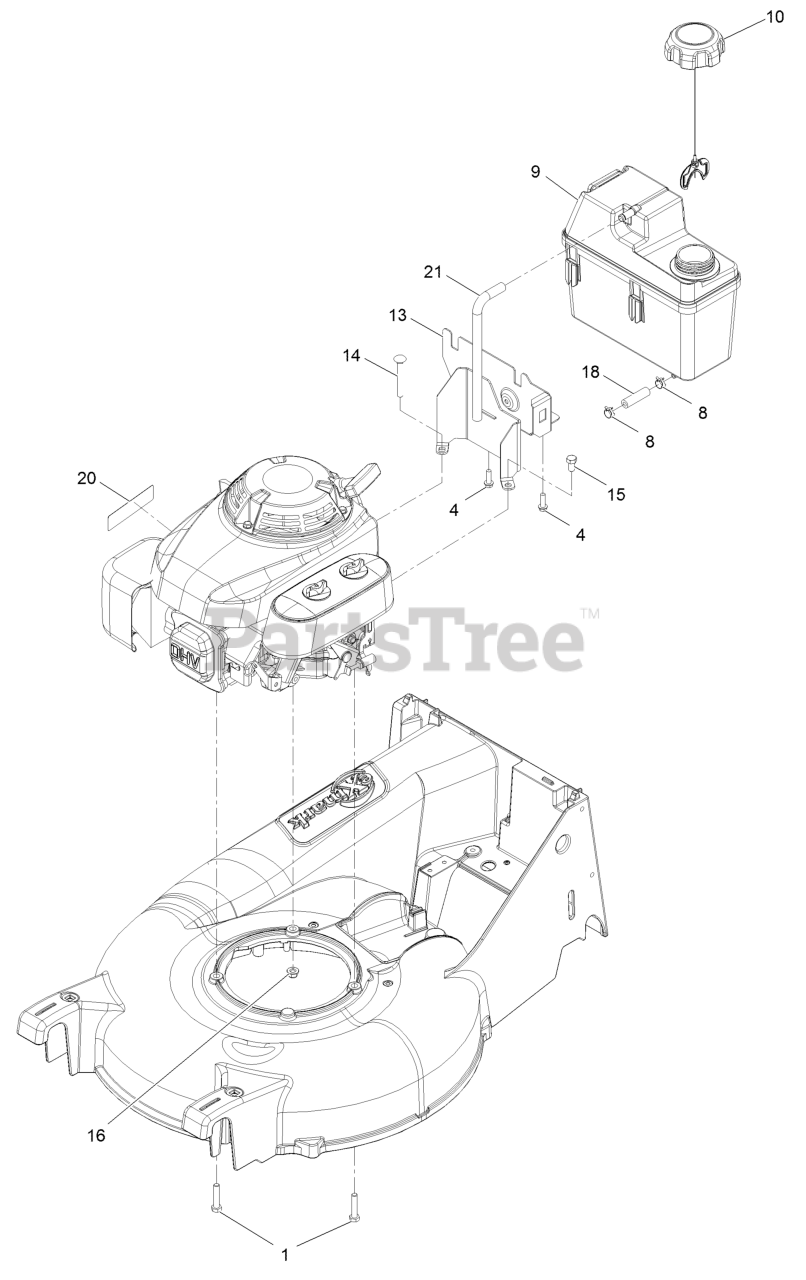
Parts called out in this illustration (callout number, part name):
1	SCREW-HH
4	SCREW-HWH
8	CLAMP-HOSE
9	TANK-FUEL
13	BRACKET ASM
14	SCREW-CARR
15	SCREW-HH
16	NUT-HF, NI
18	HOSE-FUEL
20	DECAL-ARRESTER, SPARK
21	HOSE-VENT, CANISTER
